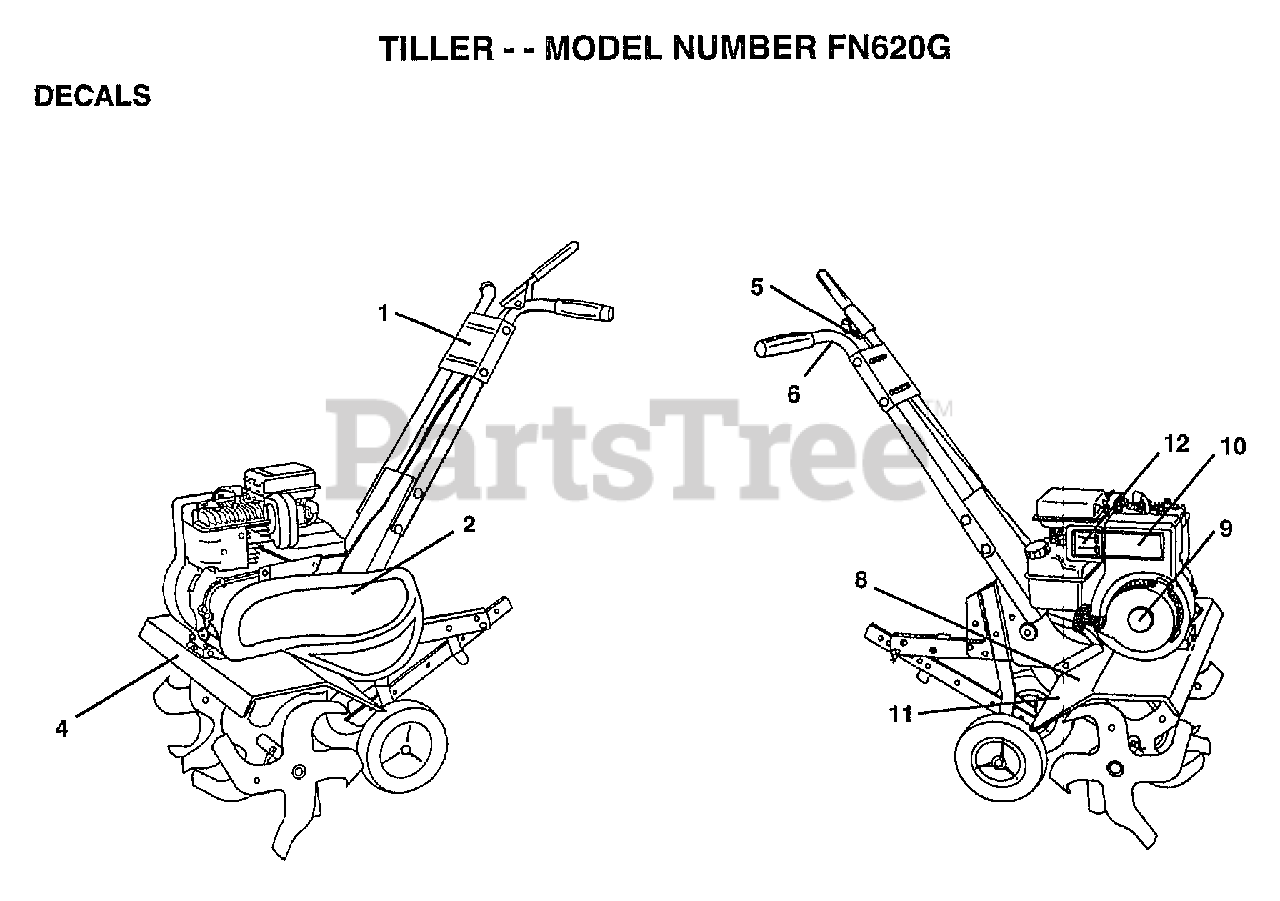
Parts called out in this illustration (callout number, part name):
1	DECAL HANDLE BRKT
4	DECAL TINE SHIELD
5	DECAL TI
6	DECAL TI
11	DECAL.CAUTION
12	DECAL.SPEED.CONTROL
